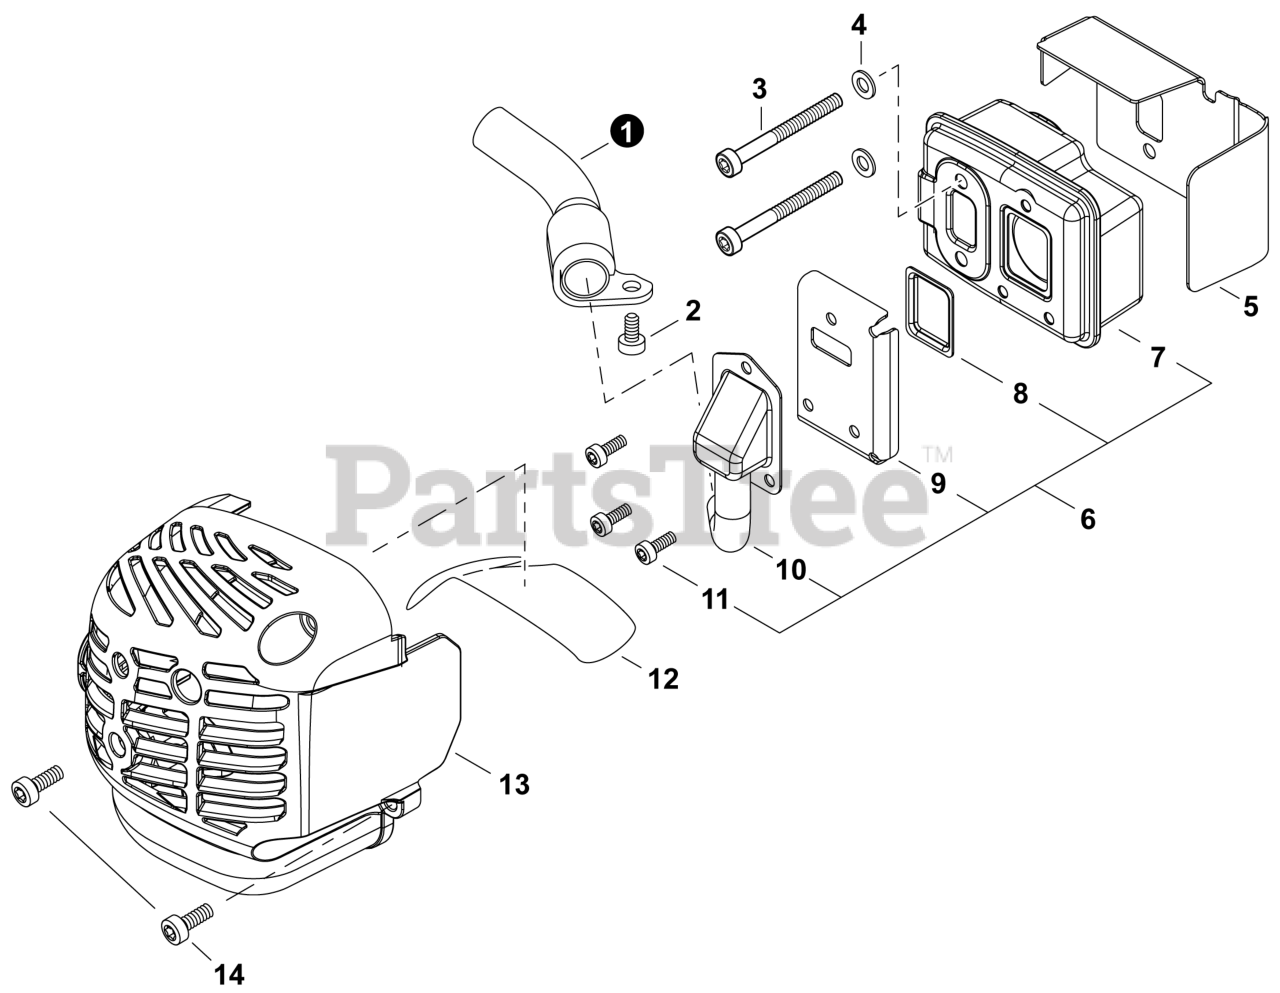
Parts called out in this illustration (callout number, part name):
1	GUIDE, EXHAUST
2	BOLT, TORX 5×10
3	BOLT, TORX 5×55
4	WASHER 5.5×12×0.8
5	HEAT SHIELD, EXHAUST
6	MUFFLER ASSY
7	MUFFLER
8	SCREEN, SPARK ARRESTER
9	GASKET, EXHAUST
10	GUIDE, EXHAUST
11	BOLT, TORX 4×8
12	PLATE, INSULATOR
13	COVER, MUFFLER
14	BOLT, TORX 5×16
